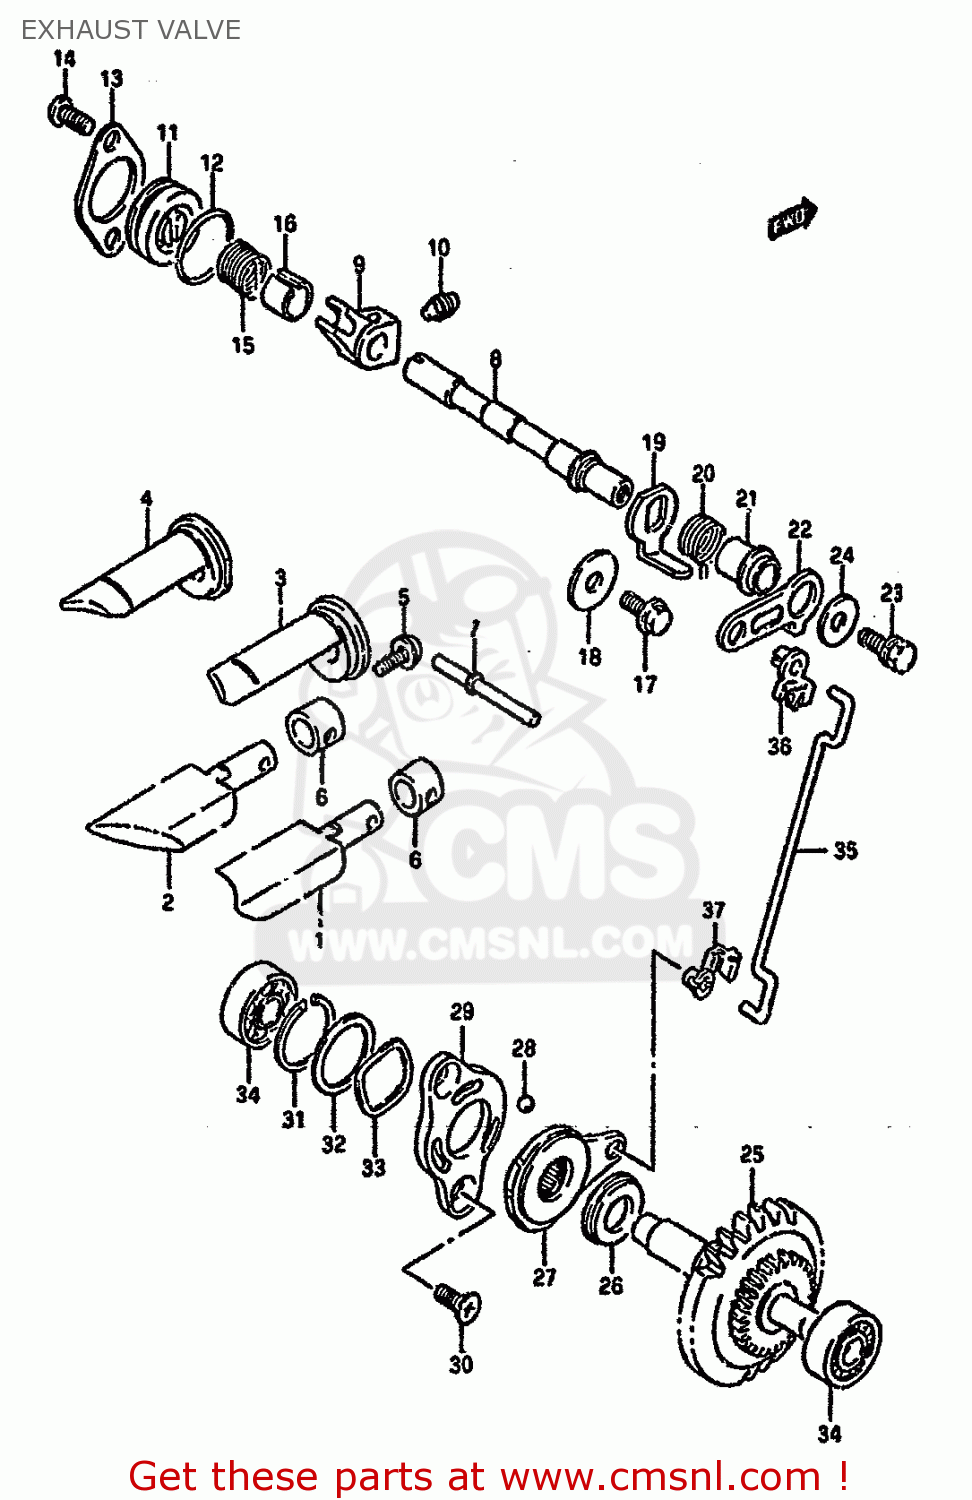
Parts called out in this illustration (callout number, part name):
1	VALVE,EXHAUST,R
2	VALVE,EXHAUST,L
3	GUIDE,EXHAUST VALVE,R
4	GUIDE,EXHAUST VALVE,L
5	SCREW
6	HOLDER,EXHAUST VALVE
7	PIN,EXHAUST VALVE 48.5MM
8	SHAFT,EXHAUST VALVE
9	ARM,EXHAUST VALVE SHAFT
10	SCREW(6X10)
11	CAP,EXHAUST VALVE
12	O RING(D:1.9,ID:22.6)
13	RETAINER,EXHAUST VALVE
14	SCREW
15	SPRING
16	SPACER,EXHAUST VALVE SPRING
17	BOLT
18	WASHER
19	LEVER,EXHAUST VALVE NO
20	SPRING
21	SPACER,EXHAUST VALVE
22	LEVER,EXHAUST VALVE NO.1
23	BOLT
24	WASHER (5.5X16X1.2)
25	GOVERNOR ASSY,EXHAUST VALVE
26	BEARING(10X22X2.8)
27	ACTUATOR,EXHAUST VALVE
28	BALL
29	STARTER,EXHAUST VALVE ACTUATOR
30	SCREW(5X10)
31	CIRCLIP
32	SHIM(19.1X25X0.3)
33	WASHER
34	BEARING(8X22X7)
35	ROD,EXHAUST VALVE
36	BUSH,EXHAUST VALVE ROD NO.1
37	BUSH,EXHAUST VALVE ROD NO.2
